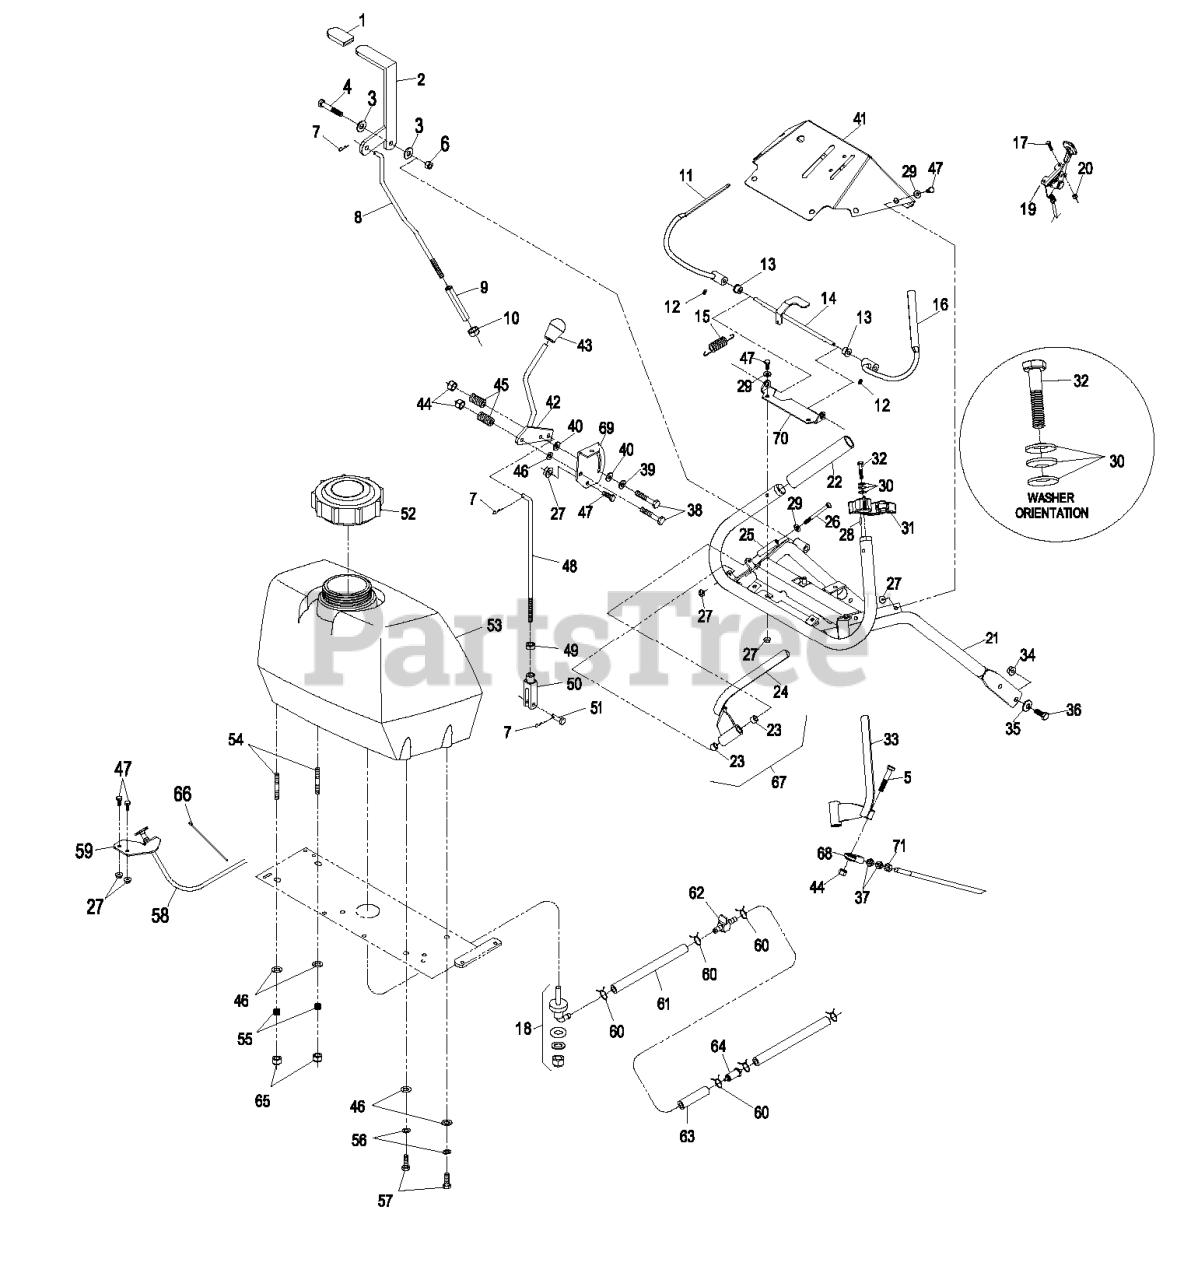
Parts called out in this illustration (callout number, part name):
1	GRIP-LEVER
3	WASHER-FLAT
4	SCREW-HH
5	SCREW-HH
6	NUT-LOCK, NI
7	PIN-COTTER
8	LINK,BLADE ENGAGE (PLTD)
9	TURNBUCKLE
10	NUT-HEX
12	SCREW-SET
13	BUSHING-NYLON
14	WLD,OPC LEVER AXLE
15	SPRING-EXTENSION
17	BOLT-CARR
18	FITTING-FUEL, BULKHEAD
19	CONTROL-THROTTLE
20	NUT-LOCK, NI
21	WLD,UPPER ECS HANDLE
22	GRIP-BAR, HANDLE
23	BUSHING-SLEEVE
25	BUSHING-LEVER, DRIVE
26	SCREW-HH
27	NUT-HF
29	WASHER-FLAT
30	WASHER-SPRING
31	ASM,LATCH RH THUMB
32	SCREW-HH
34	NUT-HHF, WHIZ
35	WASHER-BELLEVILLE
36	SCREW-HH
37	NUT-HJ
38	SCREW-HH
39	WASHER-FRICTION
40	WASHER-FRICTION
41	ASM,CONSOLE W/DECALS
43	KNOB, FE.LCKG. BLACK
44	NUT-LOCK, NI
45	SPRING-COMPRESSION
46	WASHER-PLAIN
47	SCREW-HH
48	ROD,SPEED CONTROL
49	NUT-JAM
50	YOKE-ADJUSTABLE
51	PIN-CLEVIS
52	CAP-FUEL, GAS
53	ASM,FUEL TANK W/B
54	STUD
55	SPRING-TANK, FUEL
56	WASHER-LOCK
57	SCREW-HH
58	CABLE-CHOKE
59	BRACKET-CABLE, CHOKE
61	HOSE-FUEL
62	VALVE-FUEL
63	HOSE-FUEL
64	Pn 41019-1055 Filter W/6" Fuel Line
65	NUT-LOCK, NI
66	TIE-CABLE
67	DRIVE LEVER-ASM, RH
68	JOINT-BALL, END
69	BRACKET,SHIFTER SLIDE (PL
70	BRACKET,OPC AXLE
71	NUT-HEX
